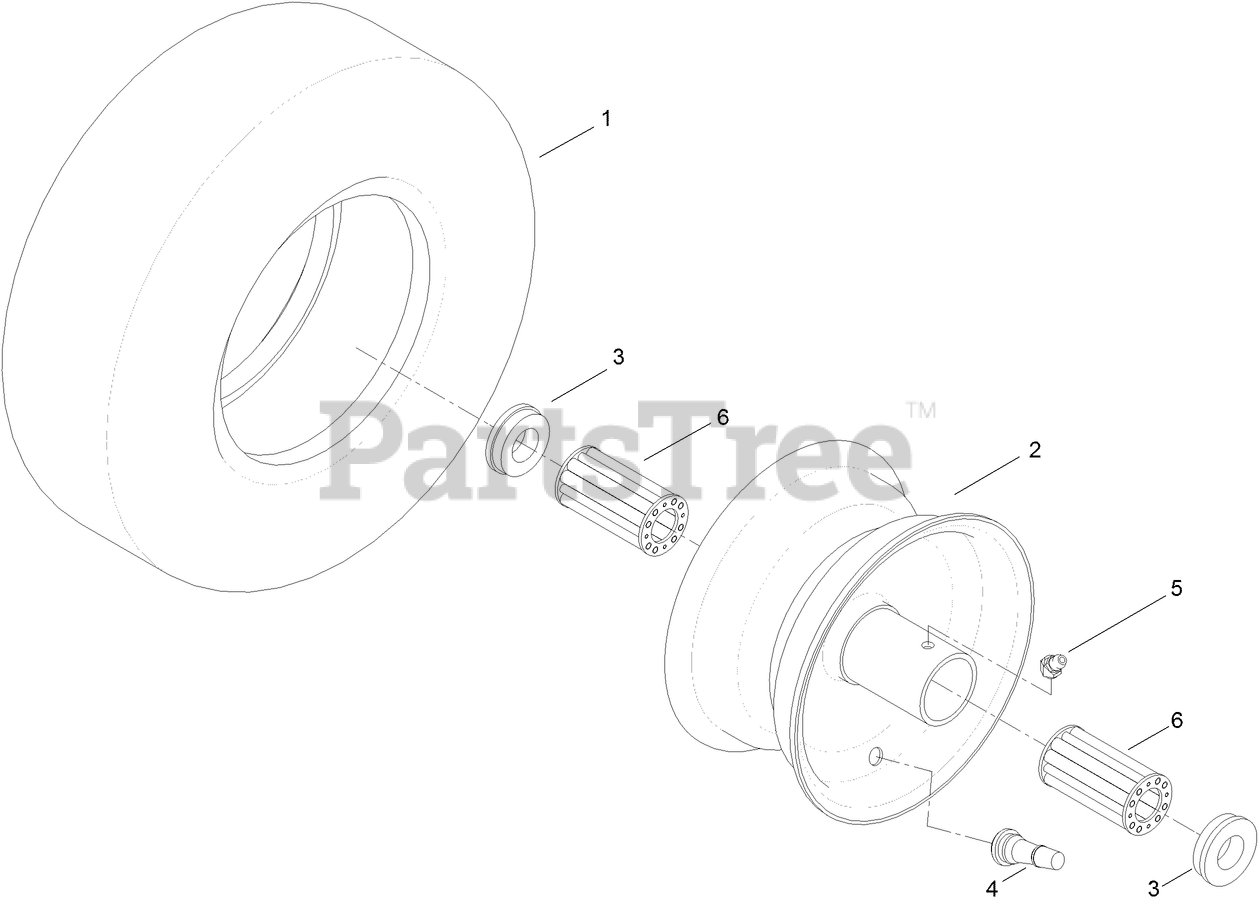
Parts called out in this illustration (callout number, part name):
2	RIM-6 INCH
4	VALVE
5	FITTING-ZERK
6	BEARING
